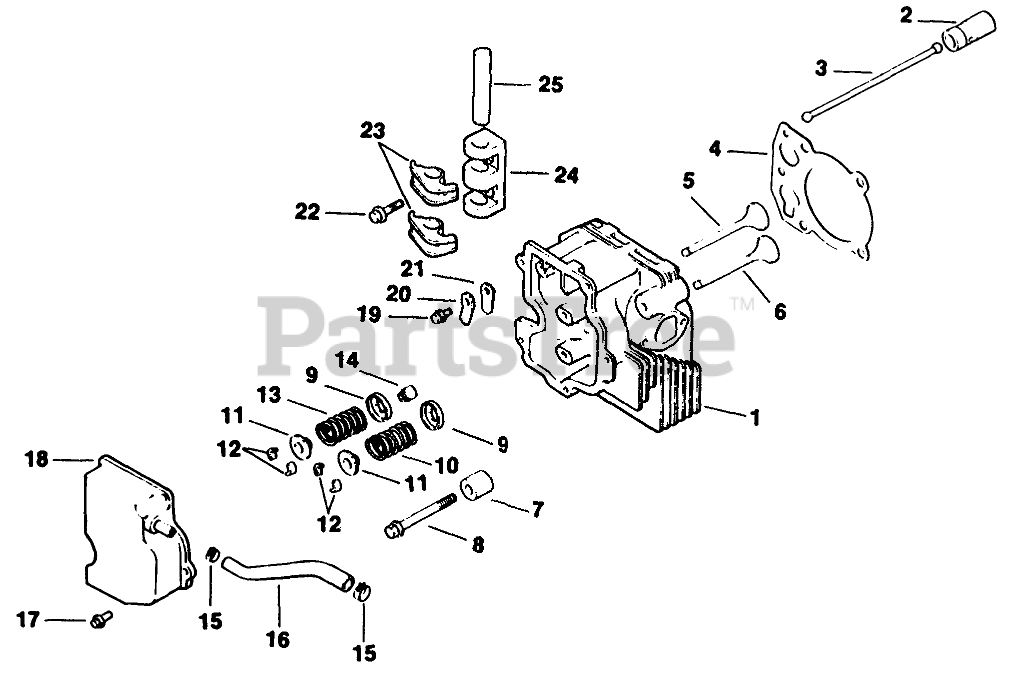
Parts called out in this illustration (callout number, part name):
1	Cylinder Head
2	Lifter-Valve
3	Rod-Push
4	Gasket-Cylinder Head
5	Valve-Intake STD
6	Valve-Exhaust STD
7	Spacer
8	Screw
9	Retainer-Spring
10	Pulley
11	Cap-Valve Spring
12	Kit-Retainer
13	Spring-Valve Intake
14	Seal
15	Clamp
16	Hose-Breather
17	Screw
18	Cover-Valve
20	Retainer-Reed
22	Screw
23	Arm-Rocker
24	Bridge-Rocker Arm
25	Shaft-Rocker Arm
26	Washer
